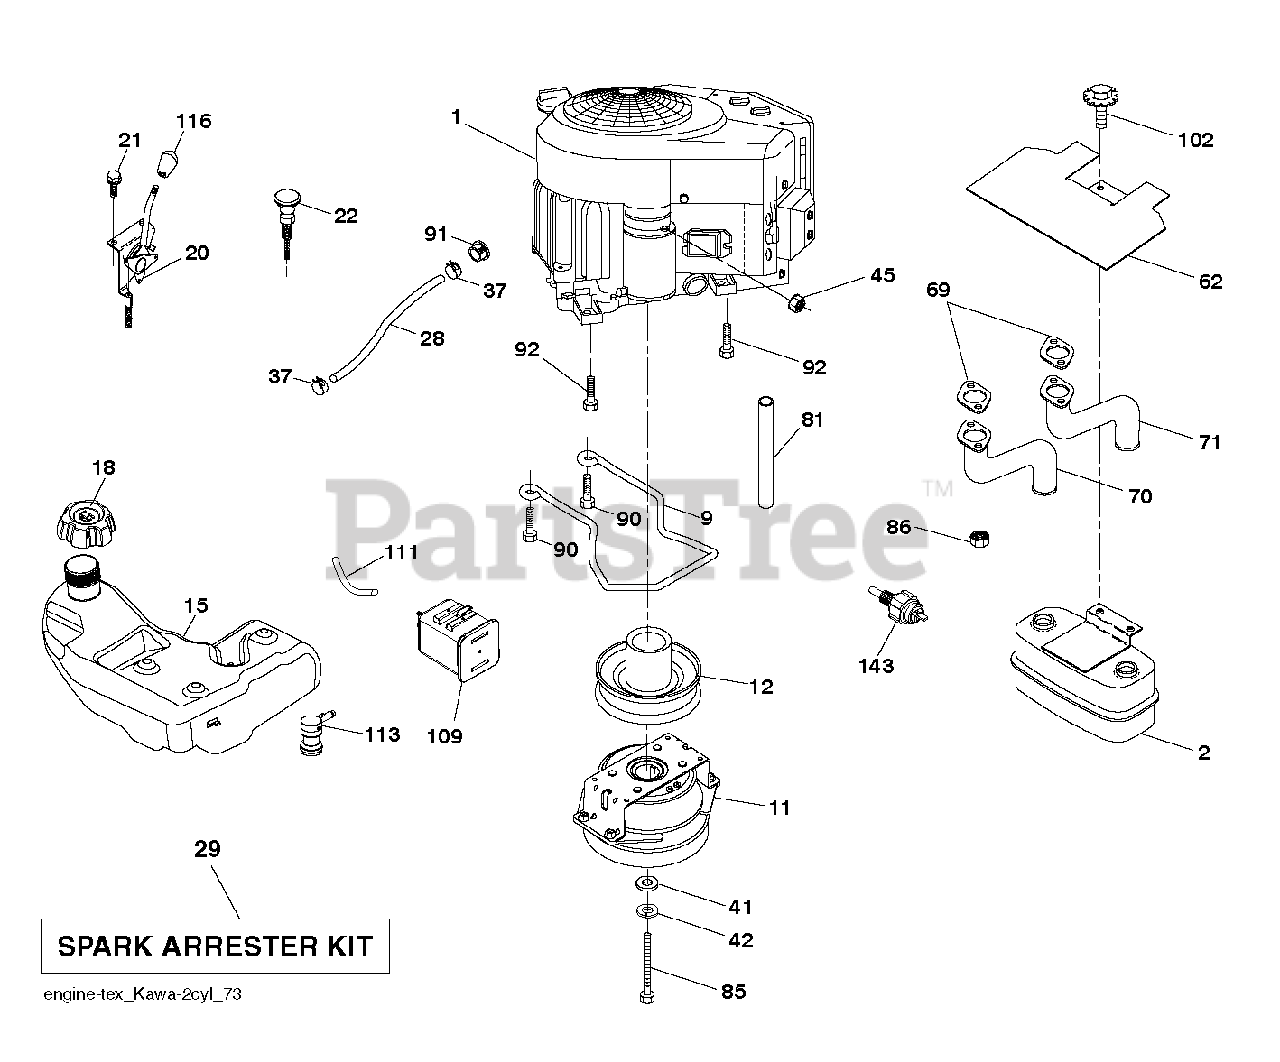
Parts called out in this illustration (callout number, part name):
2	Muffler Assembly, Twin MN
9	KEEPER.BELT.ENG.4.25"2.BLT.431
11	CLUTCH.OGURA.5.0PD.GT1.5A-EH01
12	PULLEY ENGINE
15	TANK SUBASM; 4 GAL MFG YEAR 20
18	CAP ASSY FUEL 3" GRAY
20	CONTROL.THROTTLE.PRO.
21	SCREW.#10 X 0.750.BOS
22	CONTROL, CHOKE
28	LINE.FUEL.64"REAR.EMIS
29	KIT.SPARK ARRESTOR 794945 B&S
37	HOSE CLAMP
42	WASHER 7/16 LOCK
45	NUT
62	SHIELD.HEAT.MUFFLER
70	TUBE.EXHAUST.LH.FR961/FR730
71	TUBE.EXHAUST.RH.FR961/FR730
81	TUBE, DRAIN OIL ASM.
85	BOLT.HEX.7/16-20X3.GR5.YELLOW
86	NUT.HEX.FLANGE.TOPLOCK
90	SCREW 3/8-16X1
91	BUSHING.1.375OD
92	SCREW 3/8-16X1
102	SCREW
109	CANNISTER, CARBON
111	RP PURGE LINE
113	VALVE.SLANT.CARTRDG.90 DEG.TEX
143	SENSOR.SWITCH.PRESSURE.OIL
